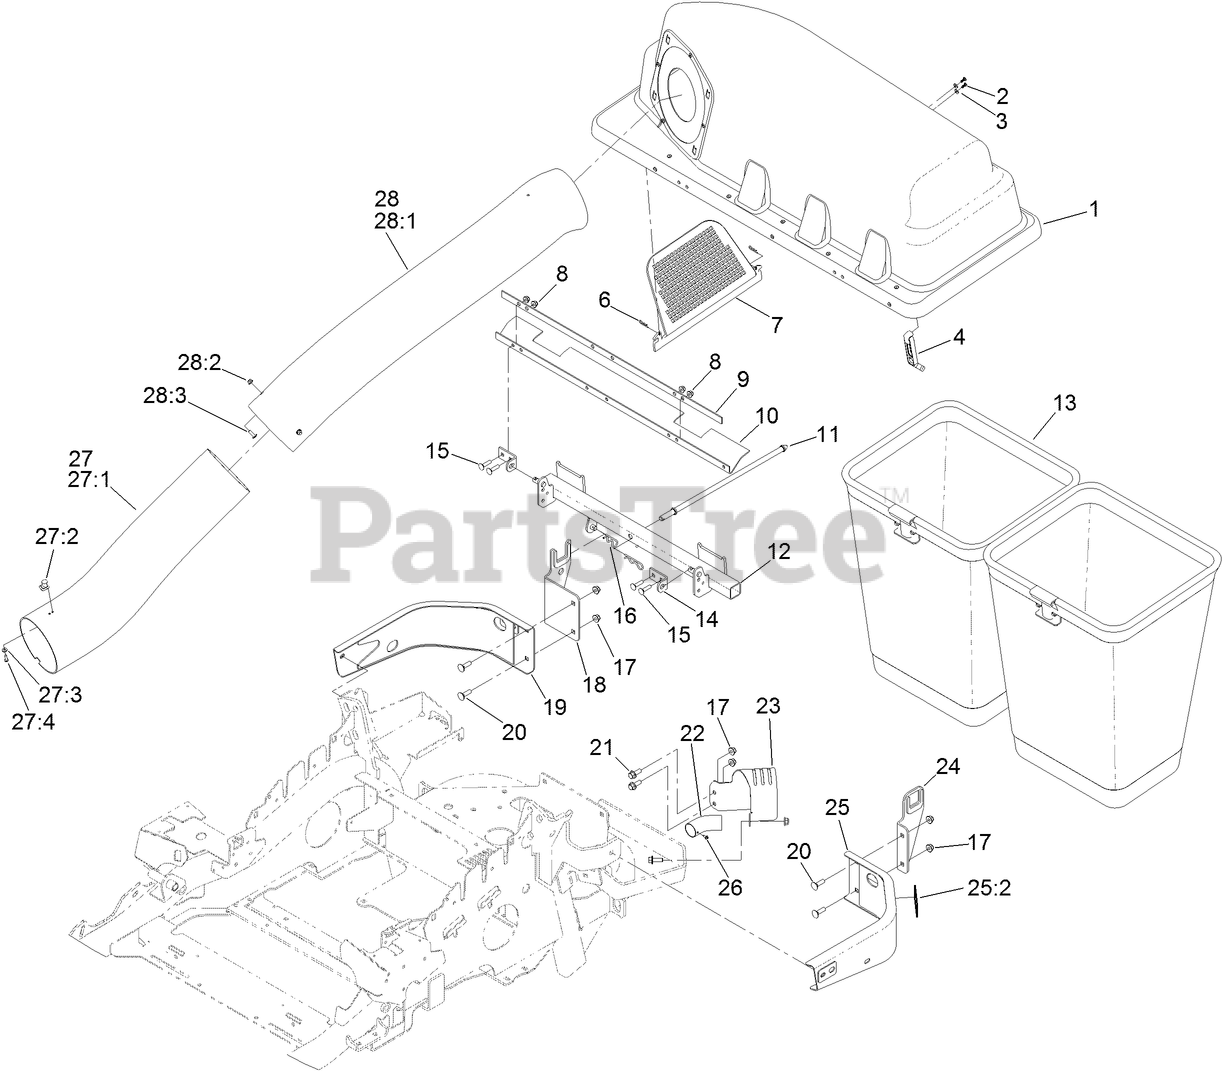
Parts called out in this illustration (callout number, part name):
1	BAGGER HOOD ASM
2	SCREW-PLASTITE
3	WASHER-FLAT
4	LATCH-RUBBER
6	PIN-COTTER
7	SCREEN-BAGGER
8	NUT-HF, NI
9	PLATE-BACKING
11	ROD-HOLD DOWN, HOOD
12	FRAME PIVOT ASM
13	BAG AND FRAME ASM
14	BRACKET-PIVOT, HOPPER
15	SCREW-CARR
16	PIN-HAIR
17	NUT-HF, NI
18	RH BAGGER BRACKET ASM
19	BUMPER-RH
20	BOLT-CARR
21	SCREW-HHF
22	TUBE-DIVERTER
23	BRACKET-DIVERTER
24	LH BAGGER BRACKET ASM
25	LH BUMPER ASM
25:2	DECAL-CAUTION
26	SCREW-THD FORM, HWH
27	LOWER TUBE ASM
27:1	TUBE-LOWER
27:2	LATCH-KEEPER
27:3	WASHER-FLAT
27:4	SCREW-PPH
28	UPPER TUBE ASM
28:1	TUBE-UPPER
28:2	NUT-HF
